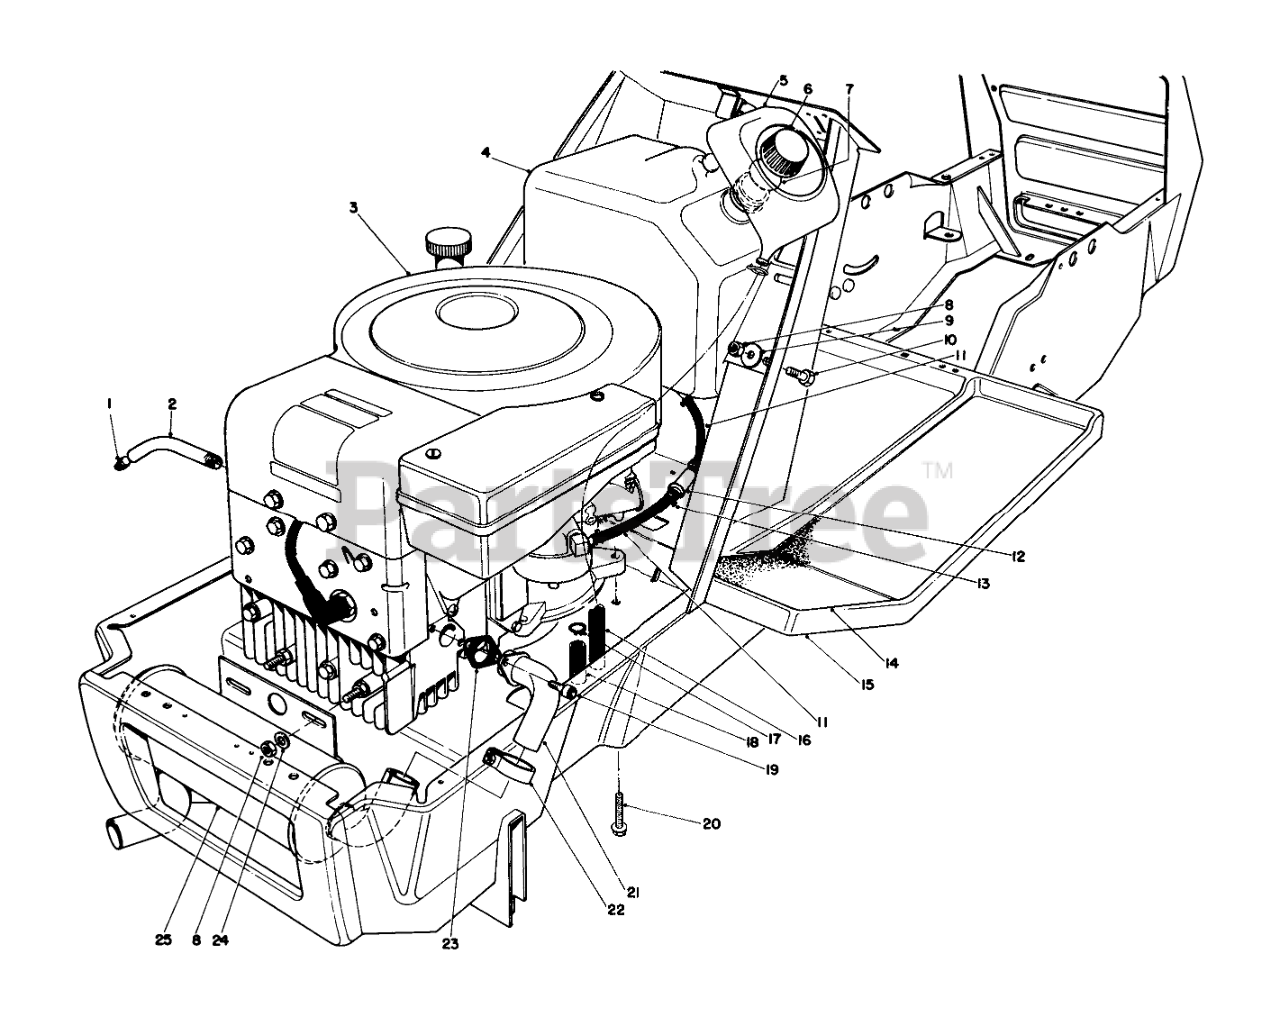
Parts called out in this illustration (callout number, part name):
1	PLUG-PIPE, SQH
2	OIL DRAIN TUBE
3	Engine (Model #57351)
4	Gas Tank
5	Funnel Overflow
6	Gas Cap (Incl. Ref. #7)
7	Gasket Gas Cap
8	NUT-LOCK, CONE
9	WASHER
10	SCREW-HH
11	Hose Gas
12	Fuel Filter
13	Clamp
14	LH FOOT TREAD
15	Frame
16	Hose Funnel
17	HOSE CLAMP
18	Hose Carburetor Drain
19	SCREW-HSH
20	SCREW-HWHTF
21	10 HP EXHAUST PIPE WA
22	MUFFLER CLAMP
23	Gasket Exhaust (Model #57351)
24	WASHER-PLAIN
25	EXHAUST MUFFLER 10 HP
